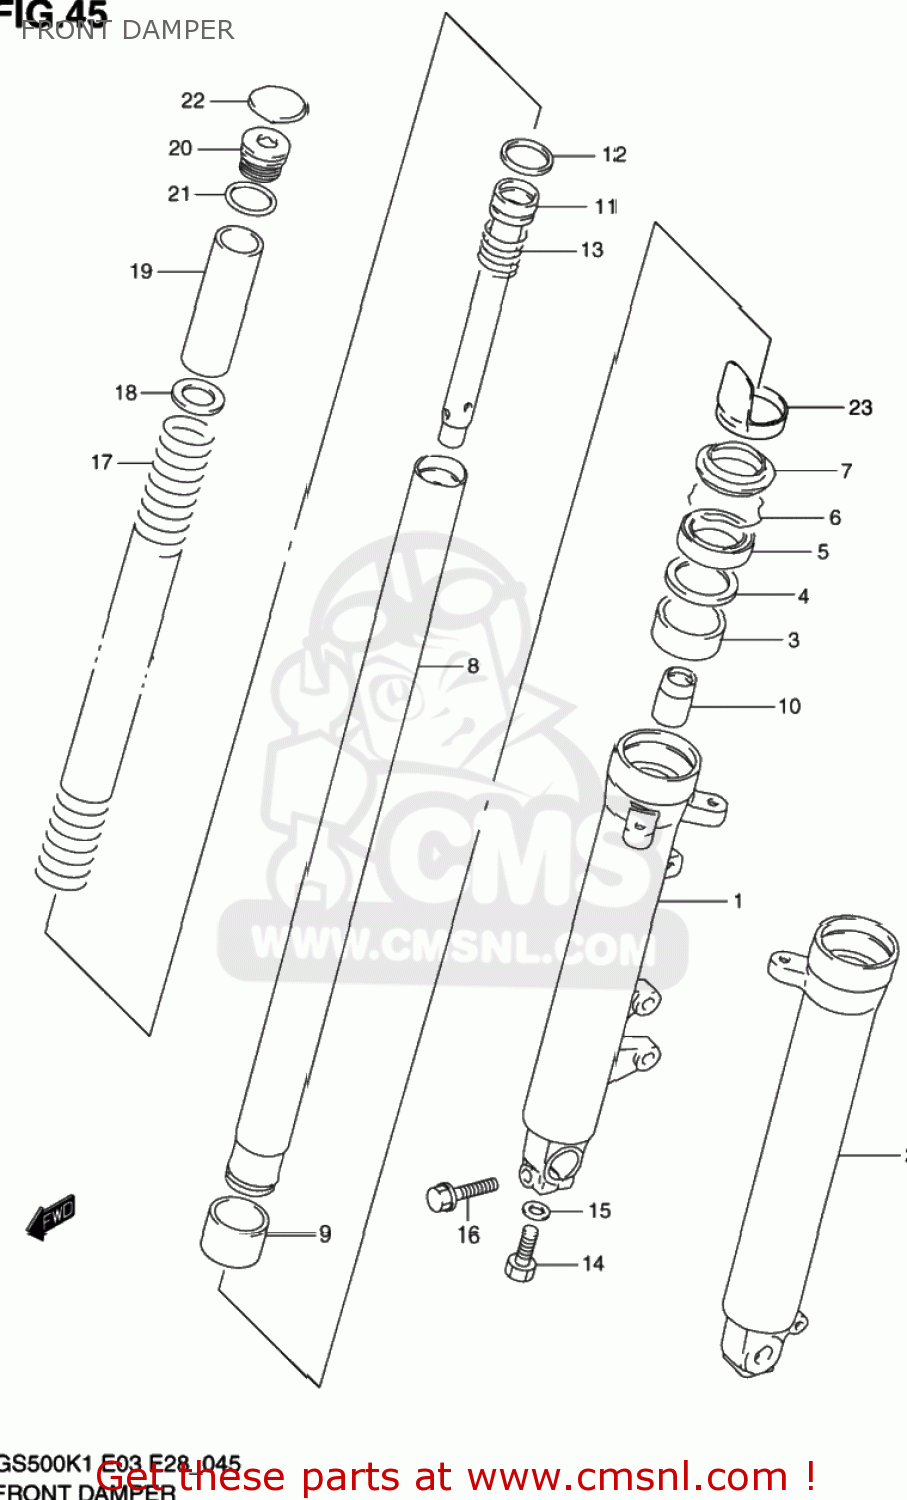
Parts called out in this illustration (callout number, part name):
1	TUBE,OUTER,R
2	TUBE,OUTER,L
3	METAL,SLIDE
4	WASHER
5	SEAL,OIL
6	RING,STOPPER
7	SEAL,DUST
8	TUBE,INNER
9	PISTON
10	PIECE,OIL LOCK
11	CYLINDER
12	RING,PISTON
13	SPRING,REBOUND
14	BOLT,FORK CYLINDER(10X25)
15	GASKET (NAS)
16	BOLT
17	SPRING
18	WASHER
19	SPACER
20	BOLT,FORK
21	O RING
22	CAP,FR FORK
23	PROTECTOR,FR FORK
